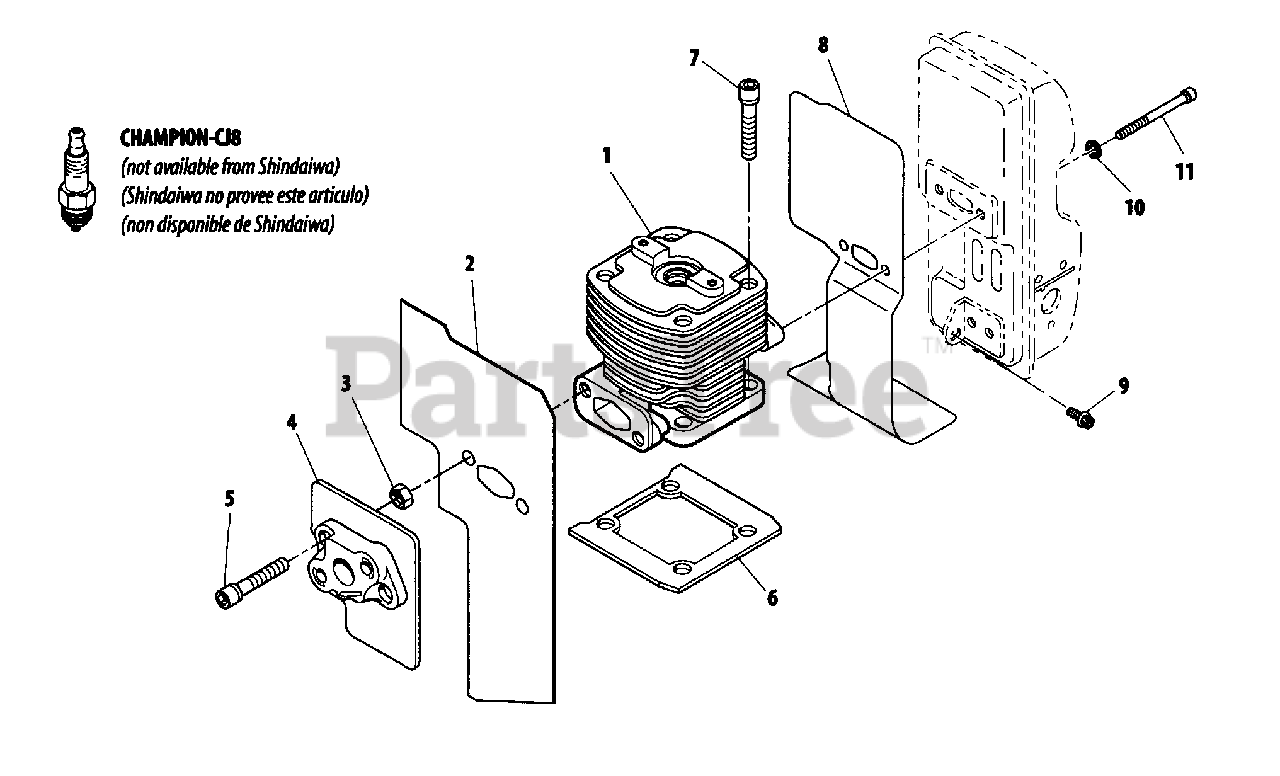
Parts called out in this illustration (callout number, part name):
1	CYLINDER
2	GASKET
3	NUT
4	INSULATOR
5	SCREW - 5X25
6	GASKET, CYLINDER
7	SCREW - 5X25
8	GASKET
9	SCREW - 5X12
10	WASHER - 6
11	SCREW - 6X70
